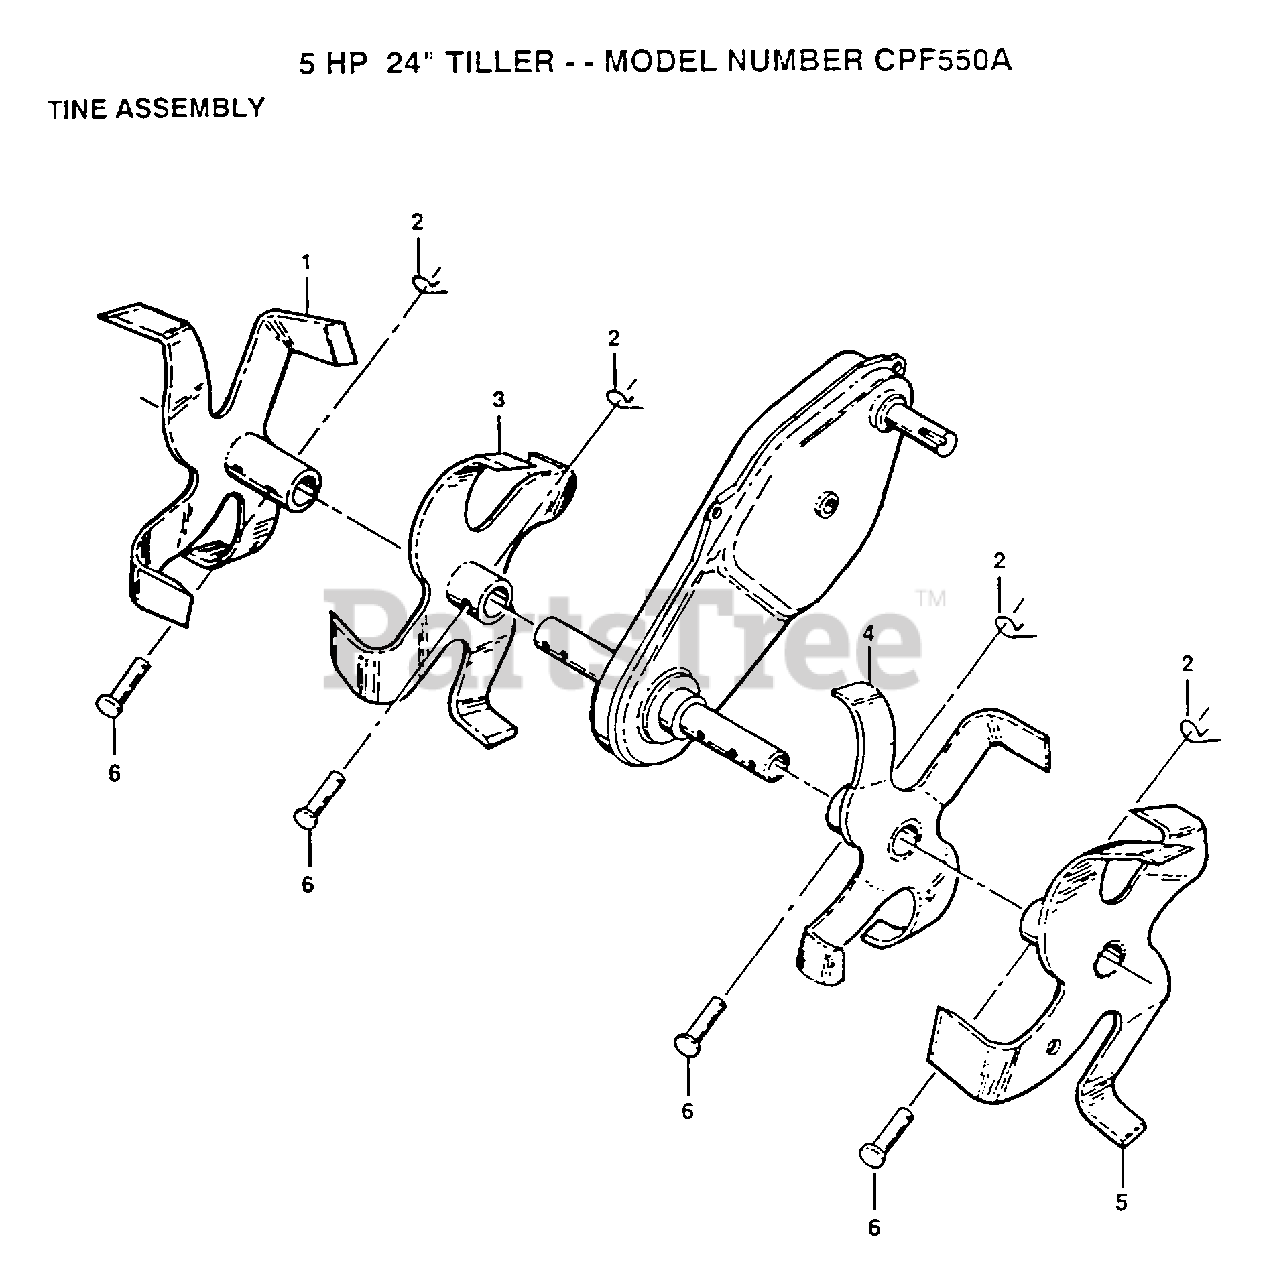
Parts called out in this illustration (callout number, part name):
1	BOLT.HEX.5/16-1.5
2	BOLT.3/8-24X3.75
3	WASHER
4	LOCKWASHER
5	GRIPCO NUT
8	BRACKET.ENG.LH.
9	LOCKWASHER
10	NUT.HEX.5/16-18
14	SPLIT SPACER RT
16	WASHER
17	WASHER
18	LOCKWASHER
19	BOLT
